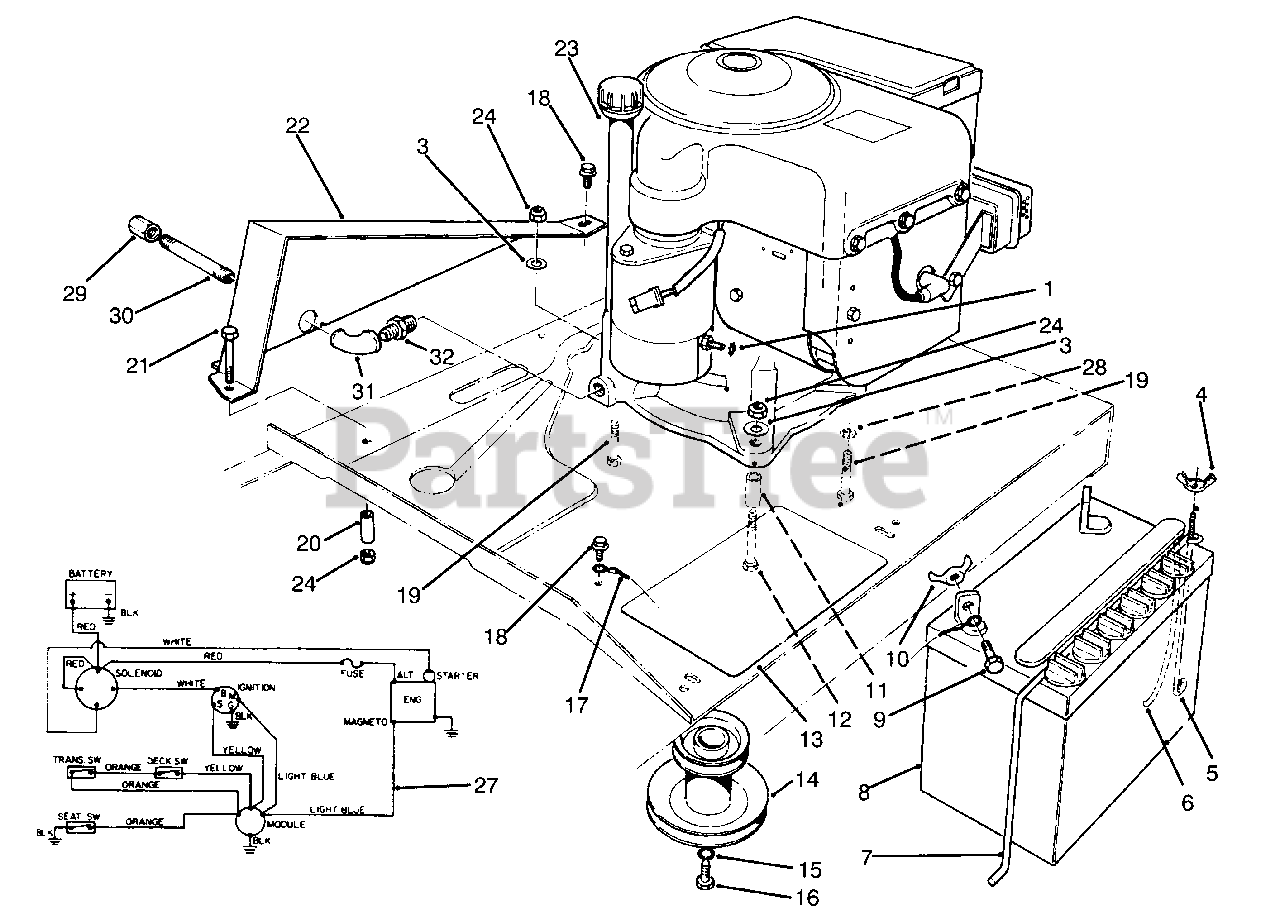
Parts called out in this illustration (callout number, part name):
1	Washer-Lock, Int. Tooth
3	Washer-Flat
5	Post-Hold Down, Battery
6	Tube-Drain
7	Hold Down-Battery
8	Battery 12V
9	Screw-Cap Hex. Hd.
12	Screw-Cap Hex. Hd.
13	Pad-Anti-Skid
14	Pulley-Engine
15	Washer-Flat
16	Screw-Cap Hex. Hd.
17	Assembly-Wire Battery to Ground
18	Screw-Self Tapping
19	Screw-Cap Hex. Hd.
20	Guide-Belt
21	Screw-Cap Hex. Hd.
22	Guard-Chain
23	Engine-8 H.P. B & S
24	Nut-Lock
27	Harness-Wire
28	Washer-Lock
29	Cap-Pipe
30	Nipple-Pipe
31	Elbow-Street
32	Reducer
